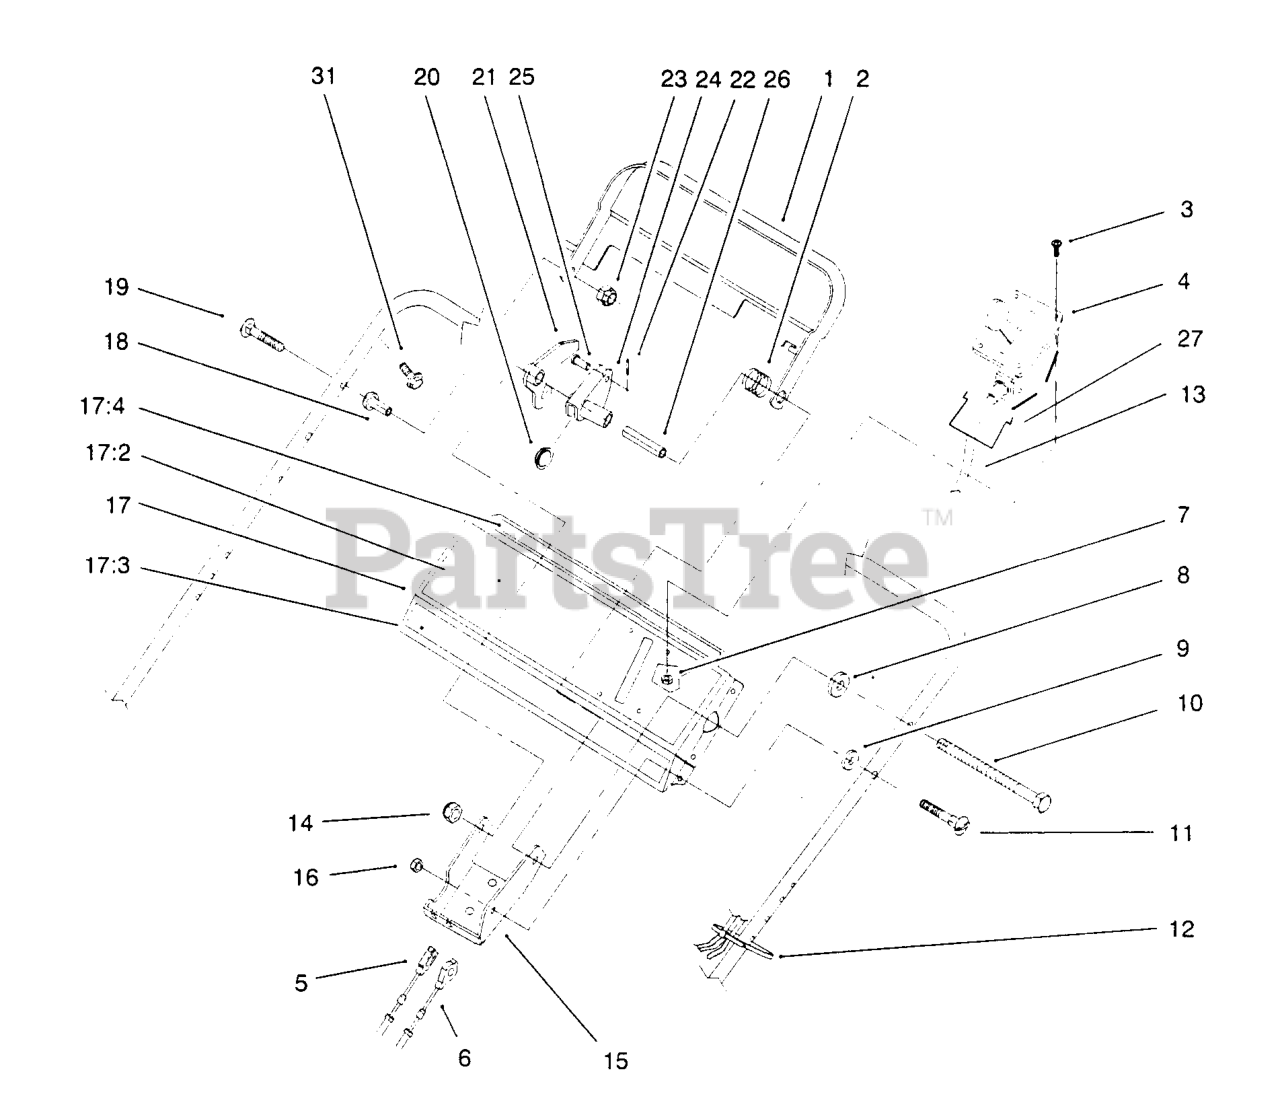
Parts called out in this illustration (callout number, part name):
1	BAR-CONTROL
2	SPRING-CONTROL
3	SCREW-PPH
4	CONTROL-THROTTLE
5	CABLE-TRACTION
6	CABLE-CLUTCH
7	NUT-LOCK, NI
10	SCREW-HH
11	SCREW-HANDLE
12	TIE-CABLE
13	CABLE-THROTTLE
14	NUT-LOCK, NI
15	BRACKET-CONTROL
16	NUT-LOCK, NI
17	PANEL-CONTROLNSP
17:2	DECAL-PANEL, CONTROL
17:4	DECAL-PANEL, DANGER
18	SPACER-SUPPORT
20	BUSHING-FLANGE
21	LEVER-TRACTION
22	PIN-COTTER
23	NUT-LOCK, NI
24	LEVER-BBC
25	PIN-CABLE
26	SPACER-BRACKET, CONTROL
27	RETAINER-CABLE, THROTTLE
31	SCREW-HWHTF
